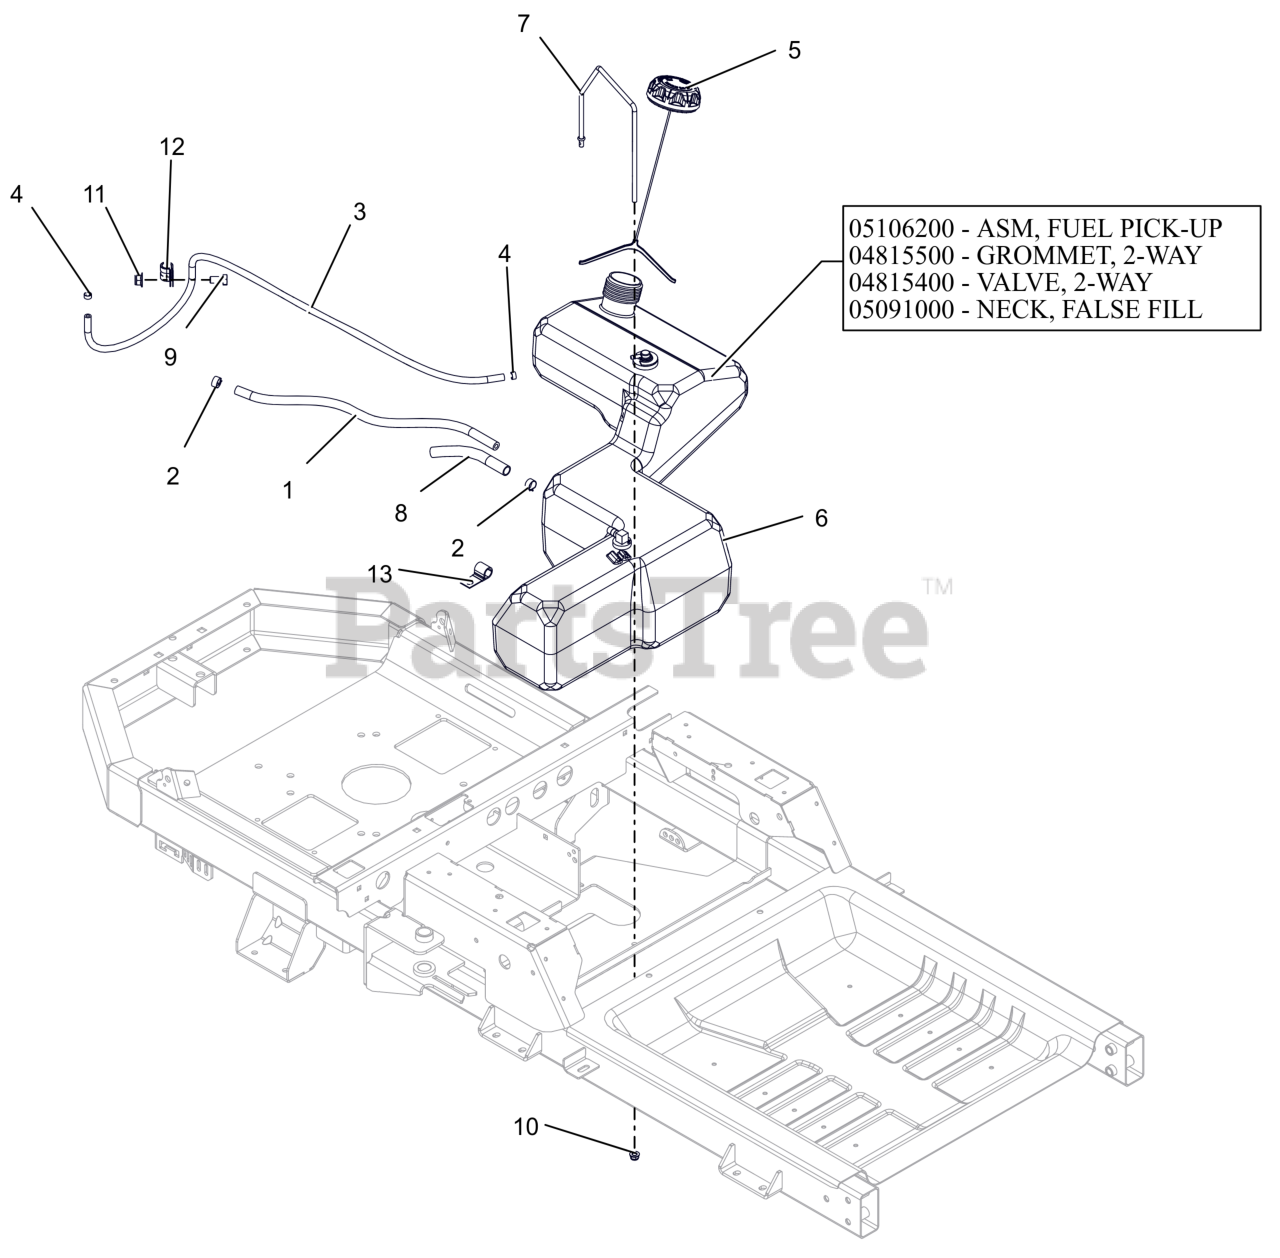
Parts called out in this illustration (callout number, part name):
1	HOSE, .25 LOW-PERM BULK GAS
2	CLAMP, FUEL LINE
3	HOSE, .188 LOW-PERM BULK GAS
4	CLAMP-HOSE, SPRING .188
5	CAP, FUEL VENT-IN 2.25" RATCH.
6	ASSEMBLY, FUEL TANK IKON(2017)
6	ASM, IKON FUEL PICK-UP
6	GROMMET, 2-WAY
6	VALVE, 2-WAY
6	NECK, FALSE FILL-2017 IKON
7	BRKT, FUEL TANK HOLD DOWN
8	WRAP, ANTIABRASION .5X.064WALL
9	@BLT-HEX .38-16X.75 GR5 YWZC
10	@NUT-LK-NYL-FLG .25-20 YWZC
11	@NUT-LK-NYL-FLG .38-16 YWZC
12	CLAMP, CUSHIONED STEEL
13	J-CLAMP
